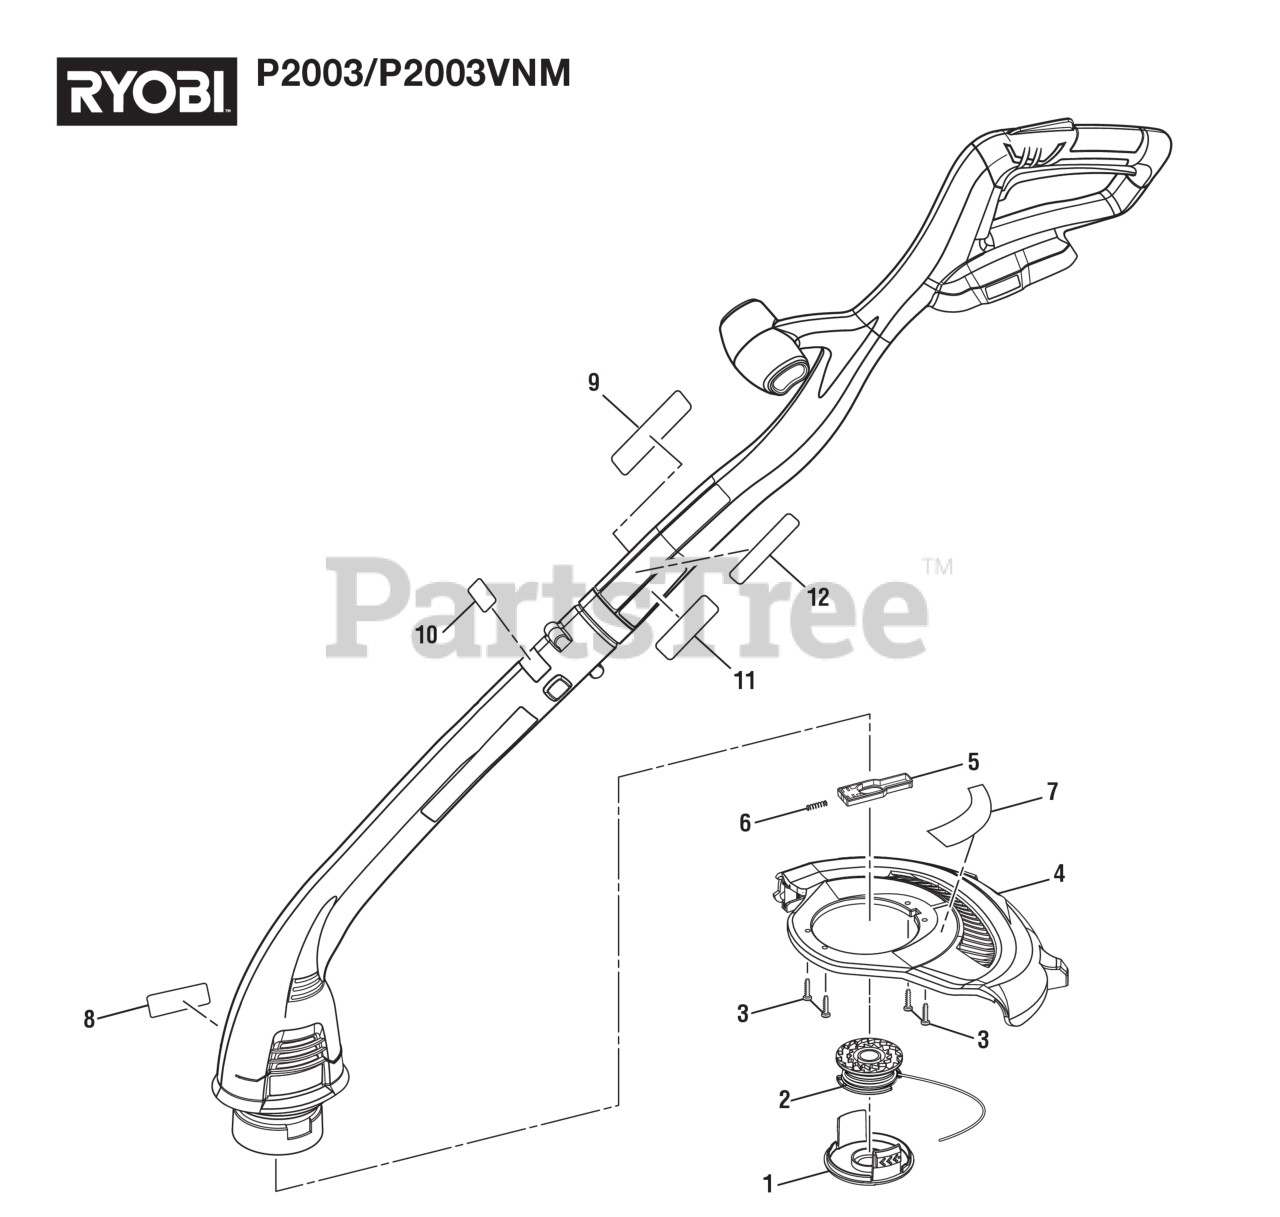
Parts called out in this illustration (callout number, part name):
1	Spool Cap (AC14HCA)
2	Spool w/Line
3	Screw (M4 x 12 mm, Pan Hd.)
4	Guard with Blade Assembly
5	Plastic Slider with Metal Inset Assembly
6	Compression Spring (Internal Tooth)
7	No Bump Label
8	Data Label (P2003VNM)
9	Label, Warning, Translation
10	Pivoting Arrow Label
11	Label, Ryobi Logo, Handle
12	Label, Warning Icon
